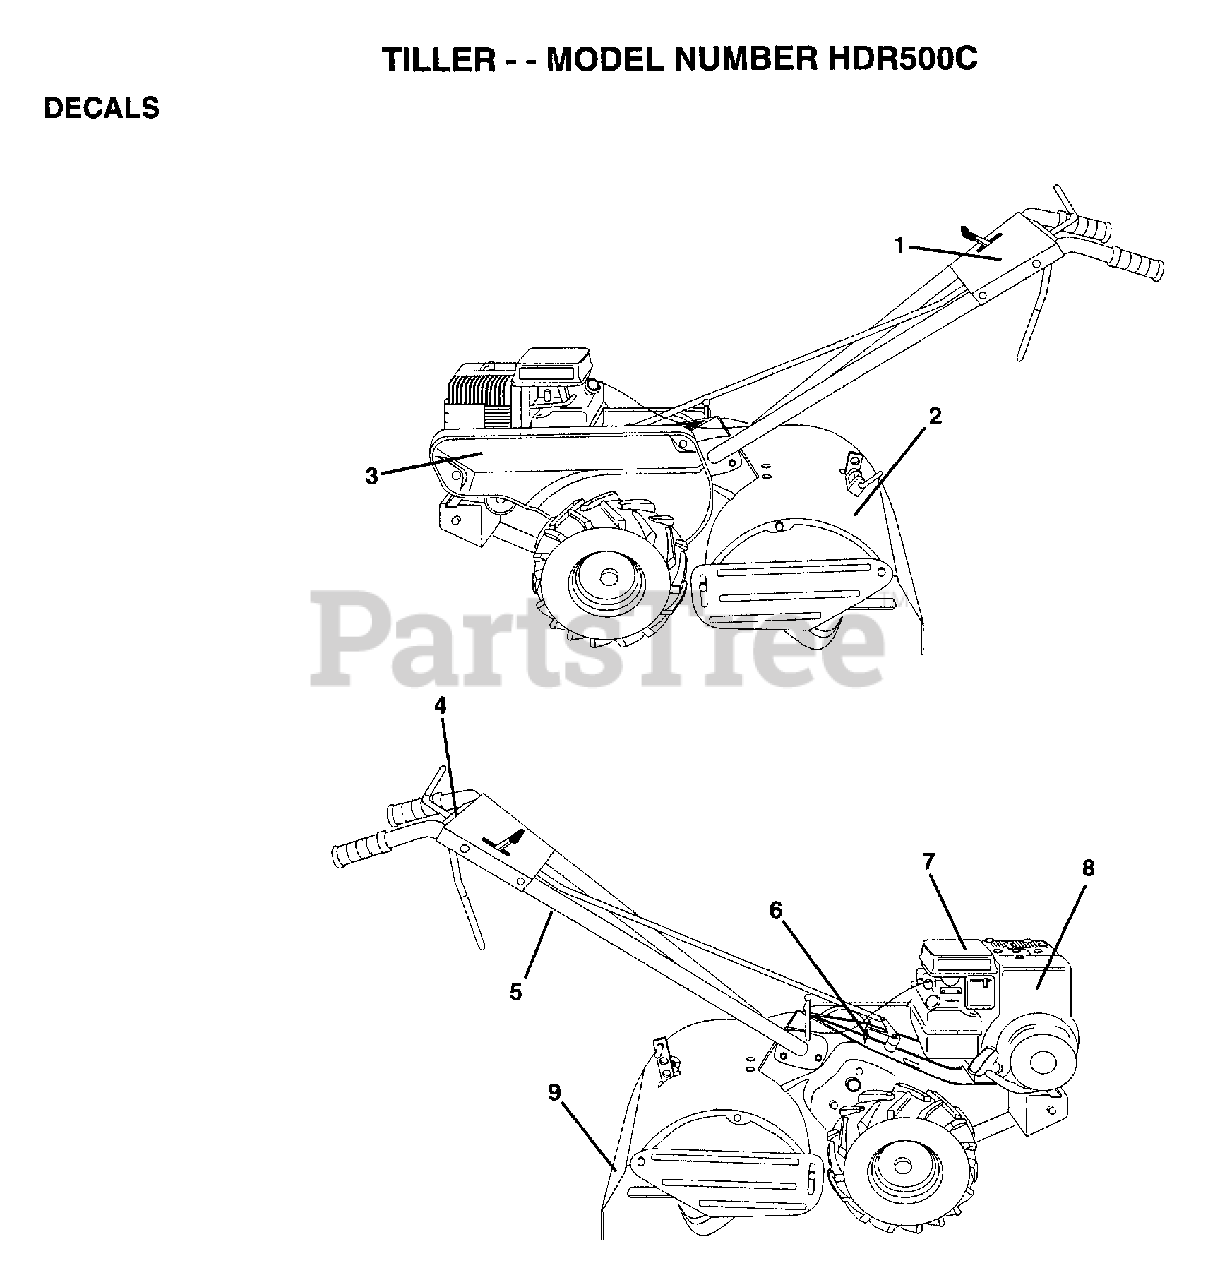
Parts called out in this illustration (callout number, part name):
1	DECAL.CNTRL.PNL.
2	DECAL.SHIELD.TINE
3	DECAL.GRD.BLT.5HP
4	DECAL.CONTROL
5	DECAL.HAND.PLACE
6	DECAL CRT
7	DECAL.CAUTION.E/S
8	DECAL, BRIGGS & STRATTON
9	DECAL.WARN.ROT.TI
